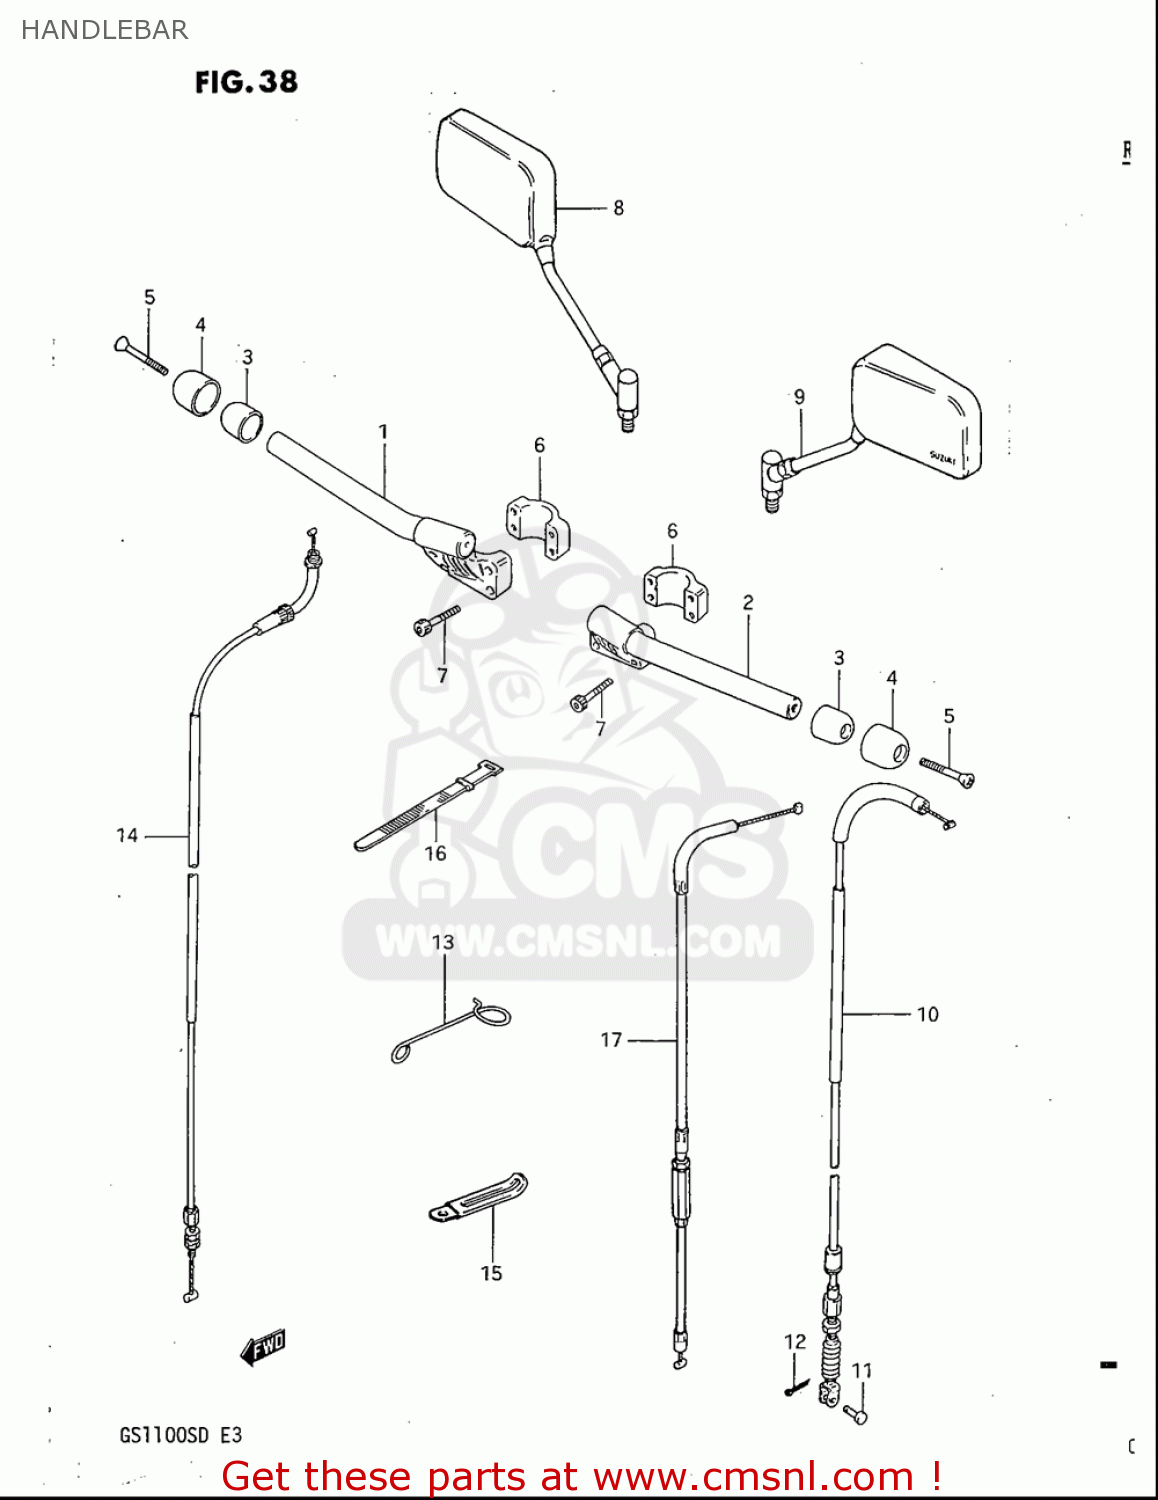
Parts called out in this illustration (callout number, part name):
1	HANDLEBAR,R
3	BALANCER,HANDLEBAR
4	CAP,HANDLE BALANCER
5	SCREW
7	BOLT
8	MIRROR ASSY,RR VIEW,R
9	MIRROR ASSY,RR VIEW,L
10	CABLE ASSY,CLUTCH
11	PIN(L:15)
12	PIN
13	GUIDE,CLUTCH CABLE
14	CABLE ASSY,THROTTLE
15	CLAMP(L:65)
16	CLAMP(L:120)
17	CABLE,CLUTCH
